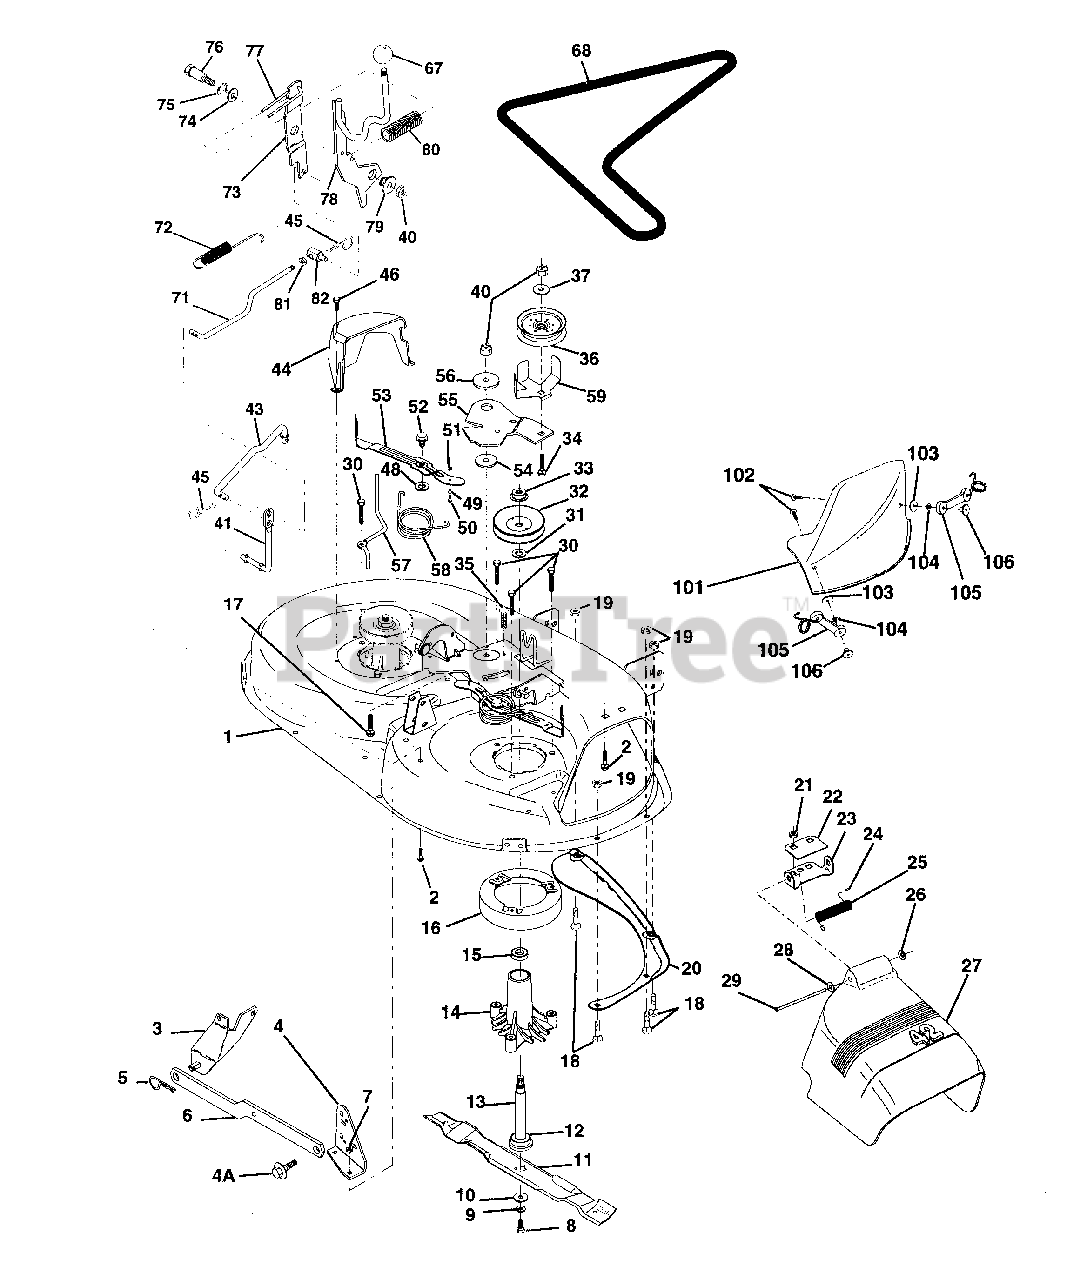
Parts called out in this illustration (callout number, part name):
1	Deck Asm Mower 42"
2	Bolt Rdhd Sqnk 5/16-18unc X3/4
3	Bracket Asm Fr Sway Bar
4	Bracket Asm Deck Sway Bar 42"
4A	Bolt Shoulder 5/16 - 18
5	Retainer Spring
6	Arm Suspension Rear
7	Locknut Hex W/Ins 5/16 - 18
8	Bolt 3/8-24x1 25 Gr8 Patched
9	Washer Lock Hvy 3/8 Unplated
10	Washer Hard Blade Mower Vented
11	Blade
12	Bearing Ball #6204 (Mandrel)
13	Shaft Asm W/lower Bearing
14	Housing Mandrel Vented(machd)
15	Bearing Ball Mandrel
16	Stripper Mower Vented
17	Bolt Rdhd Sqnk 3/8-16 X 1-1/4
18	Bolt Rdhd Sqnk 5/16-18 X 5/8
19	Locknut-hex W/ins 5/16-18unc P
20	Baffle Vortex 42
21	Nut Lock Hx w/Ins 5/16-18
22	Stiffener Bracket 42" deck
23	Bracket Deflector Mower 42"
24	Cap Sleeve 80x 112 Blk Mower
25	Spring Torsion Deflector 2 52
26	Nut Push Phos & Oil
27	Shield Deflector Mower 42" Blk"
28	Washer 11/32 X 5/8 X 16 Ga
29	Rod Hinge 42" 6 75 Wig
30	Screw Thdrol Hex Head
31	Washer Spacer Mower Vented
32	Pulley Mandrel 42"
33	Nut Fig Top Lock Cntr B 9/16
34	Bolt Rdhd 3/8-16uncx1-3/4 Gr5
35	Fastner Christmas Tree
36	Pulley Idler Flat 3 060
37	Washer 13/32 X 13/16 X 16 Ga
40	Nut Lock Hx w/Wsh 3/8-16 Unc
41	Rod Pivot W/nibs
43	Rod Clutch Secondary W/nibs
44	Guard Mandrel LH Black
45	Spring Retainer 1" Zinc/cad
46	Screw Hex Thd Cut 1/4-20x5/8 T
48	Washer Hardened Smaller
49	Roller Asm Cam Follower 42" dec
50	Bolt Shldr 10-24 Zinc Gr 5 42"
51	Nut Lock #10-24 Unc
52	Bolt Shoulder 5/16-18
53	Arm Asm Pad Brake
54	Washer Hardened
55	Arm Idler 42" mower LT/YT
56	Spacer Retainer Pm Mower
57	Keeper Belt LH Front
58	Spring Torsion Brakes
59	Guard Tuv Idler
67	Knob Rd 1/2-13 Plstc Thds Blk
68	V-Belt Mower 42" 82 625
71	Rod Clutch Primary 38/42
72	Spring Return
73	Arm Clutch Secondary
74	Washer 25/32 X 1-5/8 X 16 Ga
75	Ring Klip #t5304-75
76	Bolt Shoulder 3/8-16 Unc 1 44
77	Keeper Spring 4 000
78	Arm Asm Clutch Primary
79	Bushing 747 Od X 794 Lg Brass
80	Spring Clutch Mower 2 750 Zinc
81	Nut Hex Jam 3/8-16 unc
82	Trunnion Adj.
101	Cover Mulching 42" Black
102	Screw
103	Washer Lock #10
104	Washer #10
105	Latch Asm Bagger
106	Nut Weld .327/.304 #10-24
